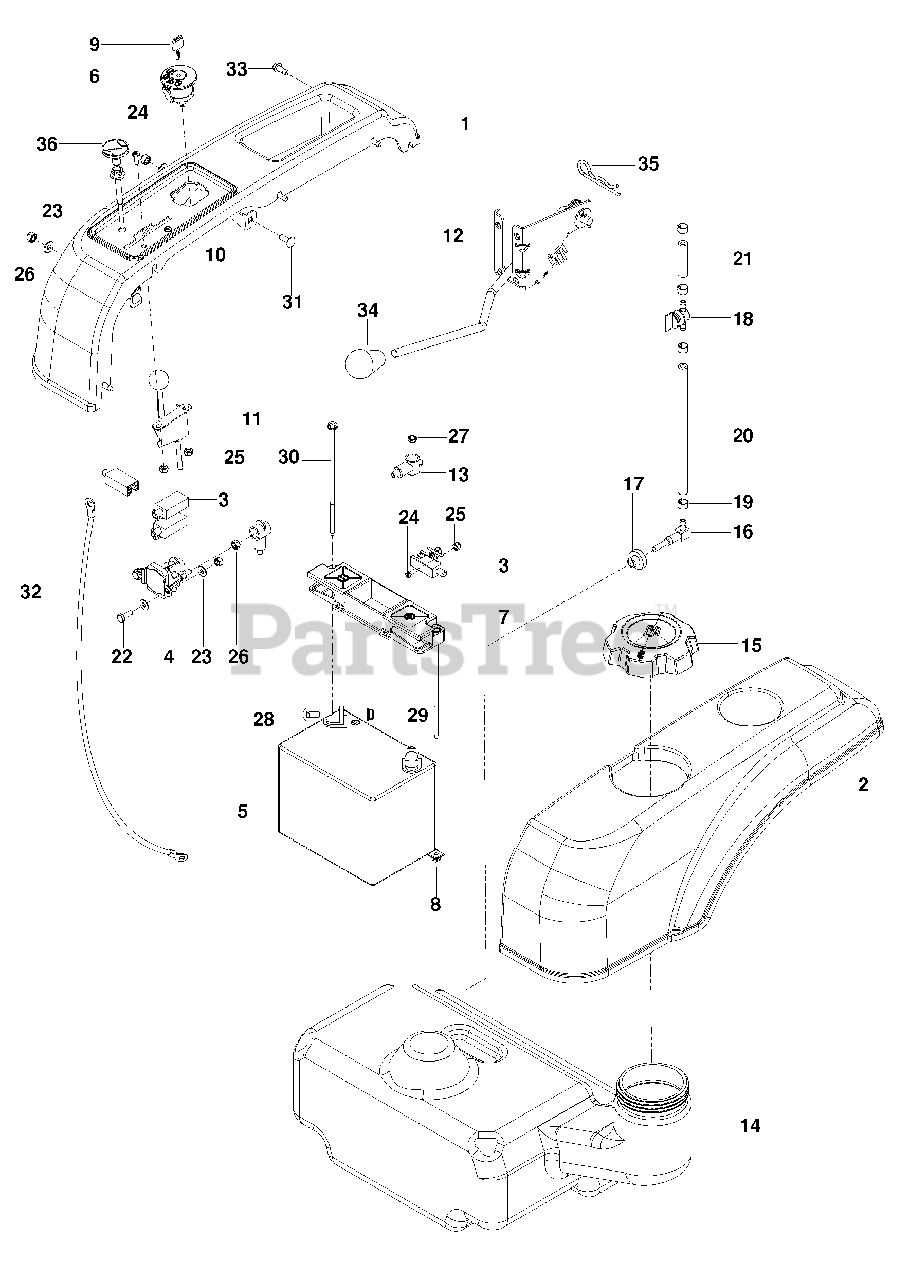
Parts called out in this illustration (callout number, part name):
1	FENDER, RH
2	FENDER, LH
5	BATTERY
6	SWITCH, IGNITION
7	BATTERY HOLD DOWN
8	NUT 1/4 PUSH NYLON
9	KEY, IGNITION
10	PANEL, CONTROLS BLK
11	CABLE, THROTTLE
12	CLUTCH ASSY w/ CABLE
13	TERMINAL COVER, SM
14	TANK, FUEL
16	ELBOW w/ FILTER
17	FITTING, TANK
18	VALVE, FUEL
19	CLAMP, HOSE
20	HOSE 1/4 x 8
21	HOSE, 1/4 x 2
22	HCS 1/4-20 x 3/4
23	WASHER 1/4 FLT SAE
24	SCREW #10-24 x 5/8
25	NUT #10-24 HEX NYLOC
26	NUT 1/4-20 HEX NYLOC
27	NUT 1/4-20 HEX THIN NYLOC
28	RHSNB 5/16-18 x 3/4
29	NUT 5/16-18 FLANGE NYLOC
30	BOLT 1/4 x 7 1/2
31	RHSNB 1/4-20 x 3/4 GR2
32	BATTERY CABLE, NEGATIVE
33	SCREW 1/4-20 x 5/8 SLF TAP
34	GRIP, CLUTCH
35	RETAINER, SPRING
36	CABLE, CHOKE
